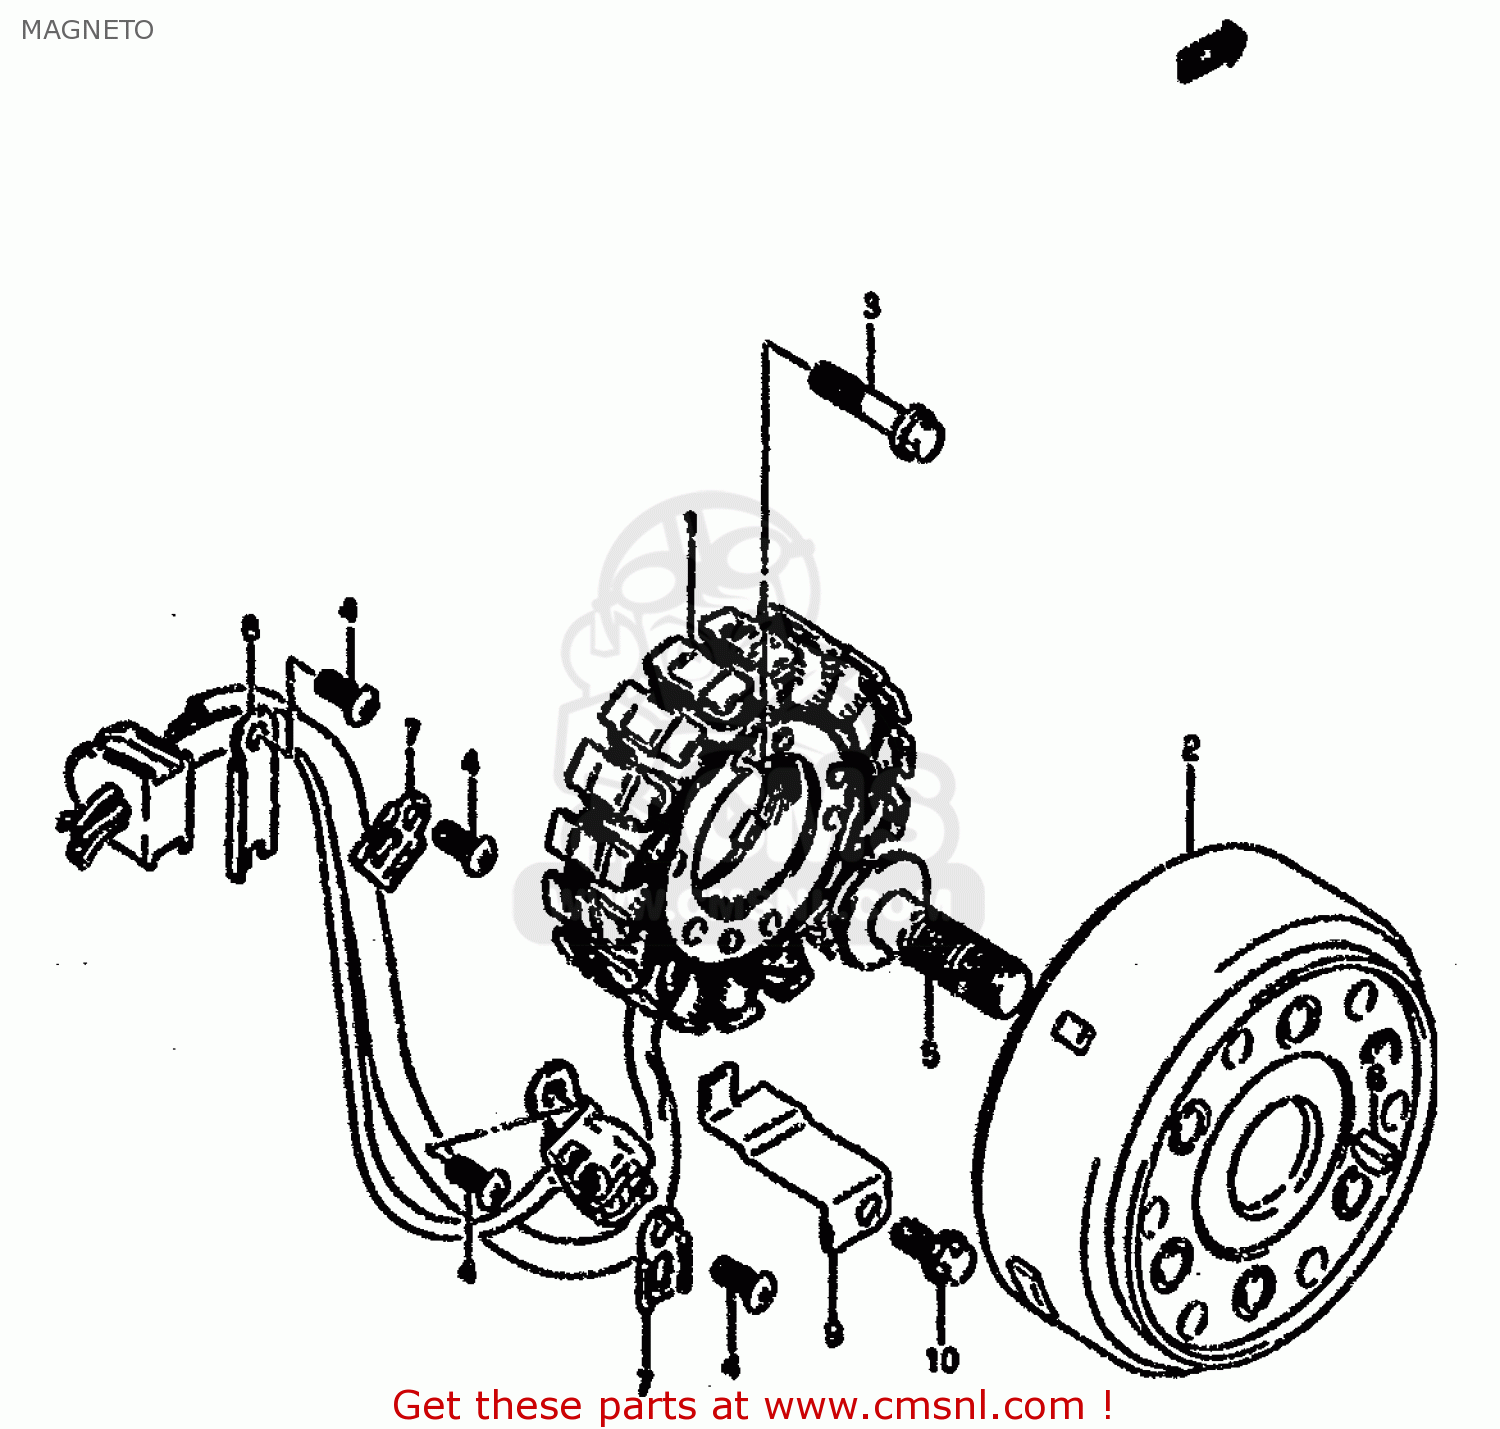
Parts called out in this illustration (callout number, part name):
1	STARTER ASSY
2	ROTOR ASSY
3	BOLT,G/S SWITC
4	SCREW
5	BOLT(14X43)
6	KEY
7	CLAMP,GENERATOR LEAD WIRE
8	CLAMP NO.1,MAGNETO READ WIRE
9	CLAMP,MAGNETO LEAD WIRE
10	BOLT
